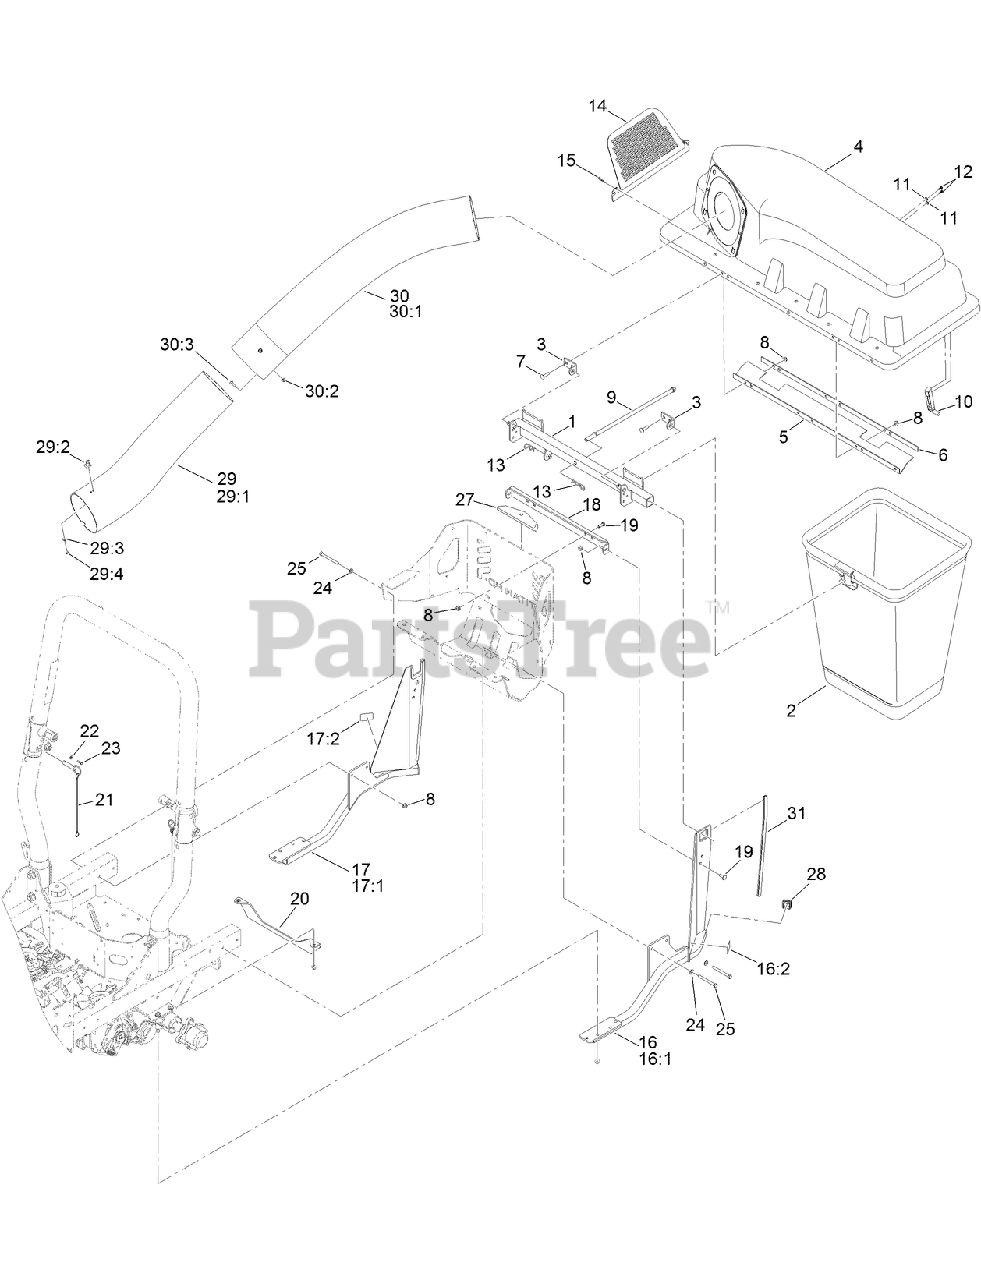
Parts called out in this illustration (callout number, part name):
1	FRAME PIVOT ASM
2	BAG AND FRAME ASM
3	BRACKET-PIVOT, HOPPER
4	BAGGER HOOD ASM
6	PLATE-BACKING
7	SCREW-CARR
8	NUT-HF, NI
9	ROD-HOLD DOWN, HOOD
10	LATCH-RUBBER
11	WASHER-FLAT
12	SCREW-PLASTITE
13	PIN-HAIR
14	SCREEN-BAGGER
16	RH BAGGER SUPPORT ASM
16:1	SUPPORT-BAGGER, RH
16:2	DECAL-WARNING
17	LH BAGGER SUPPORT ASM
17:1	SUPPORT-BAGGER, LH
17:2	DECAL-WARNING
18	ANGLE - SUPPORT, BAGGER
19	SCREW-HH
20	SUPPORT-TRANSMISSION
21	HITCH PIN ASM
22	WASHER-FLAT
23	SCREW
24	WASHER-PLAIN
25	SCREW-HH
27	COVER-HITCH
29	LOWER TUBE ASM
29:1	TUBE-LOWER
29:2	LATCH-KEEPER
29:3	WASHER-FLAT
29:4	SCREW-PPH
30	UPPER TUBE ASM
30:1	TUBE-UPPER
30:2	NUT-HF
31	STRIP-TRIM
